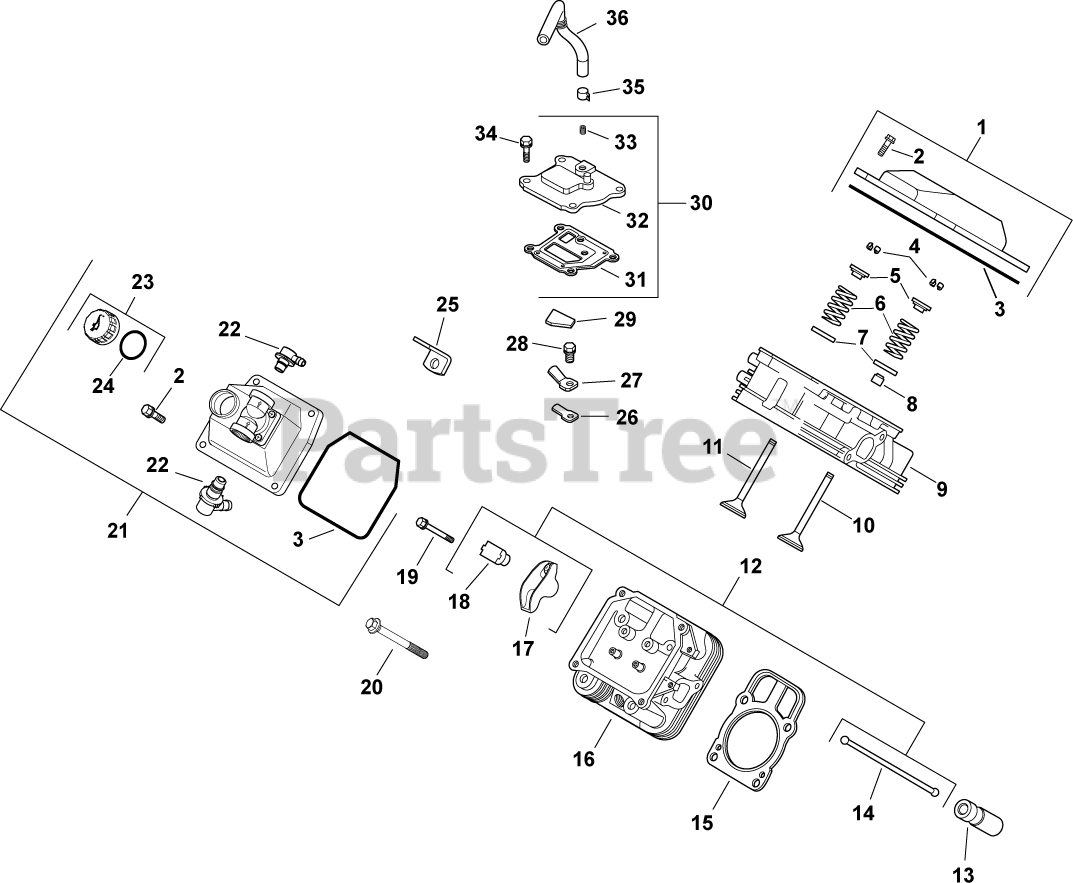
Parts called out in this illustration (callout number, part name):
1	KIT, VALVE COVER-PLAIN
2	SCREW, FLG M6X1.0X30
3	O-RING (YELLOW), VALVE COVER
4	KIT, RETAINER
5	RETAINER, VALVE SPRING - USE 25 173 28-S
6	SPRING, VALVE
7	RETAINER, SPRING
8	SEAL, VALVE STEM - (#2503214S)
9	HEAD, ASSEM CYLINDER #1 -USE 24 318 107-
10	VALVE, INTAKE (STD)
11	VALVE, EXHAUST (STD) - USE 32 016 01-S
12	KIT, VALVE TRAIN
13	LIFTER, HYDRAULIC VALVE-USE 25 351 10-S
14	ROD, PUSH
15	KIT, CYL HEAD GASKET (C17-22)
16	HEAD, ASSEM CYLINDER #2 -USE 24 318 115-
17	ARM, ROCKER
18	PIVOT, ROCKER ARM
19	SCREW, FLG M6X1.0X34
20	SCREW, FLG M10X1.5X60 - DISC.
21	KIT, VALVE COVER-FUEL PUMP
22	KIT, STRAIGHT FITTING
23	CAP ASSY, OIL FILL (YELLOW)
24	O-RING-USE 24 153 32-S
25	STRAP, LIFTING-USE 25 445 03-S
26	REED, BREATHER
27	RETAINER, REED
28	SCREW, FLG THD FRM M5X.8X10
29	FILTER, BREATHER
30	KIT, BREATHER ASSEMBLY
31	GASKET, BREATHER-USE 24 041 67-S
32	COVER, BREATHER -USE 24 033 01-S
33	PLUG, CTSK PIPE 1/8"
34	SCREW,FLG THD FRM M6X1.0X20-(#25086396S)
35	CLAMP, HOSE (KM)-USE 25 237 31-S
36	HOSE, BREATHER
2401602-S	VALVE, EXHAUST (.25)
2401702-S	VALVE, INTAKE (.25)
